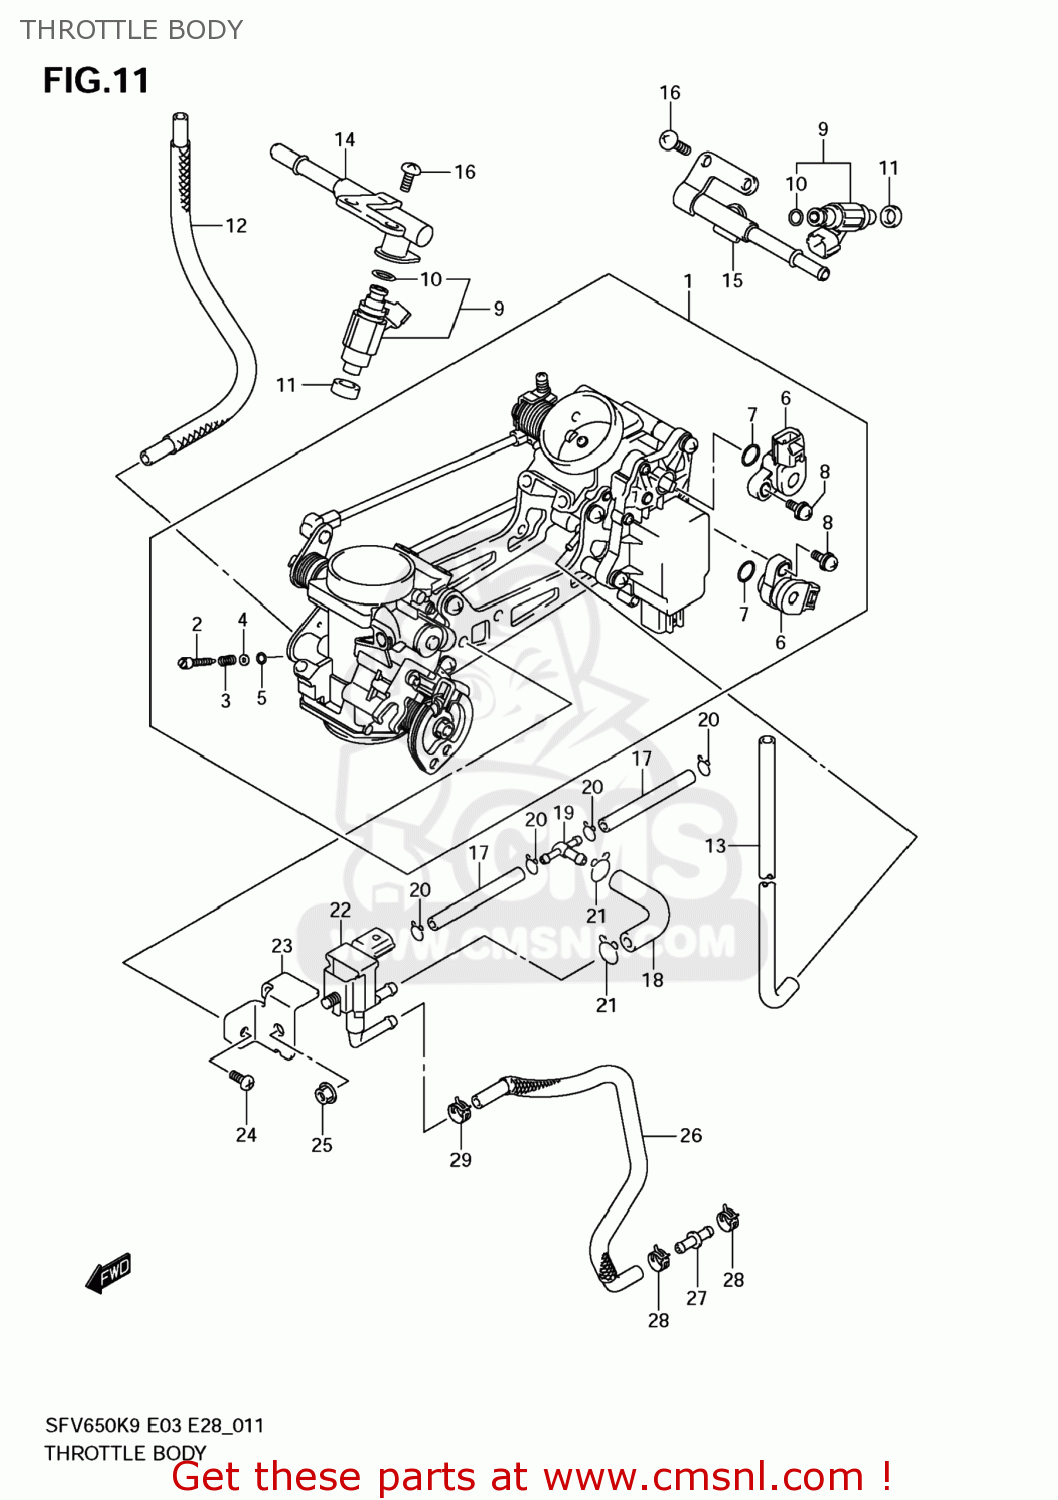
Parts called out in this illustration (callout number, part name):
1	BODY ASSY,THROTTLE
2	SCREW
3	SPRING,THROTTLE SCREW
4	WASHER
5	O RING,PILOT AIR SCREW
6	SENSOR
7	O RING
8	SCREW
9	INJECTOR ASSY
10	O RING
11	SEAL
12	HOSE
13	HOSE
14	DELIVERY PIPE
15	DELIVERY PIPE
16	SCREW
17	HOSE
18	HOSE
19	NIPPLE
20	CLIP
21	CLIP
22	VALVE,CANISTER PURGE
23	BRACKET
24	SCREW
25	NUT
26	HOSE,PURGE VALVE
27	JOINT
28	CLIP
29	CLIP
